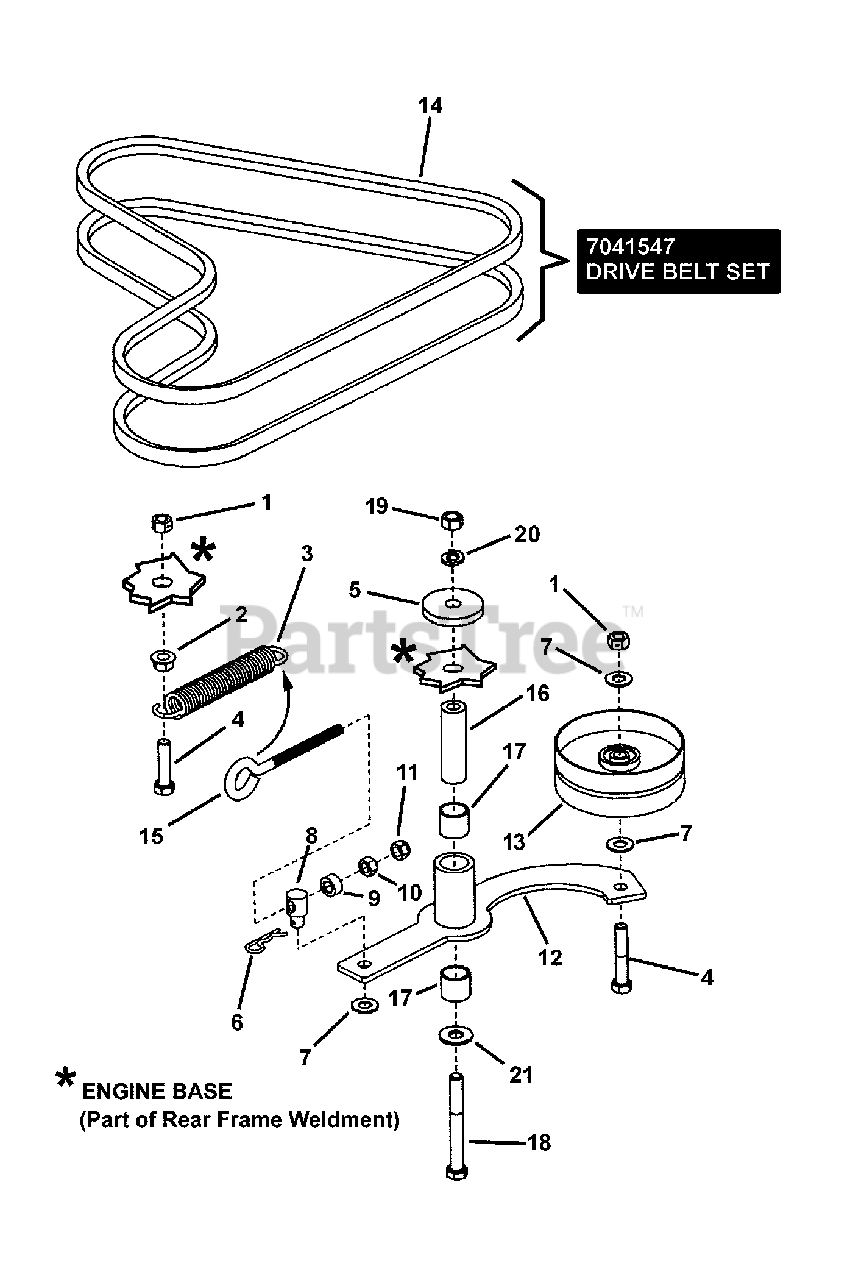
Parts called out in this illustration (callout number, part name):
1	NUT, 3/8-16 Hex Center Lock
2	NUT, 3/8-16 Hex Flange Lock
3	SPRING, Extension
4	SCREW, 3/8-16 x 1-1/2" Hex Head Cap, GR 5
5	WASHER, .468 x 1.85 x .25
6	HAIR PIN, 3/32 x 1-1/2"
7	WASHER, 3/8" Flat SAE
8	SWIVEL, Adjustable
9	SPACER, .340 I.D. x .63 O.D. x .310 Thick
10	NUT, 5/16-18 Hex, GR 5 or B
11	NUT, 5/16-18 Hex Nyloc
12	WELDMENT, Idler Arm
13	PULLEY, 4" O.D. x .391 I.D. x 1.25 Backside Idler
14	BELT, Hydro Drive (HA Section, 47.5 Effective Length)
15	EYEBOLT, 5/16-18
16	BOSS, Idler Arm Pivot
17	SLEEVE BUSHING, 3/4" I.D.
18	BOLT, 3/8-16 x 3-1/2" Hex Head, GR 5
19	NUT, 3/8-16 Hex, GR 5 or B
20	WASHER, 3/8" Split Lock
21	WASHER, 3/8" Flat SAE
